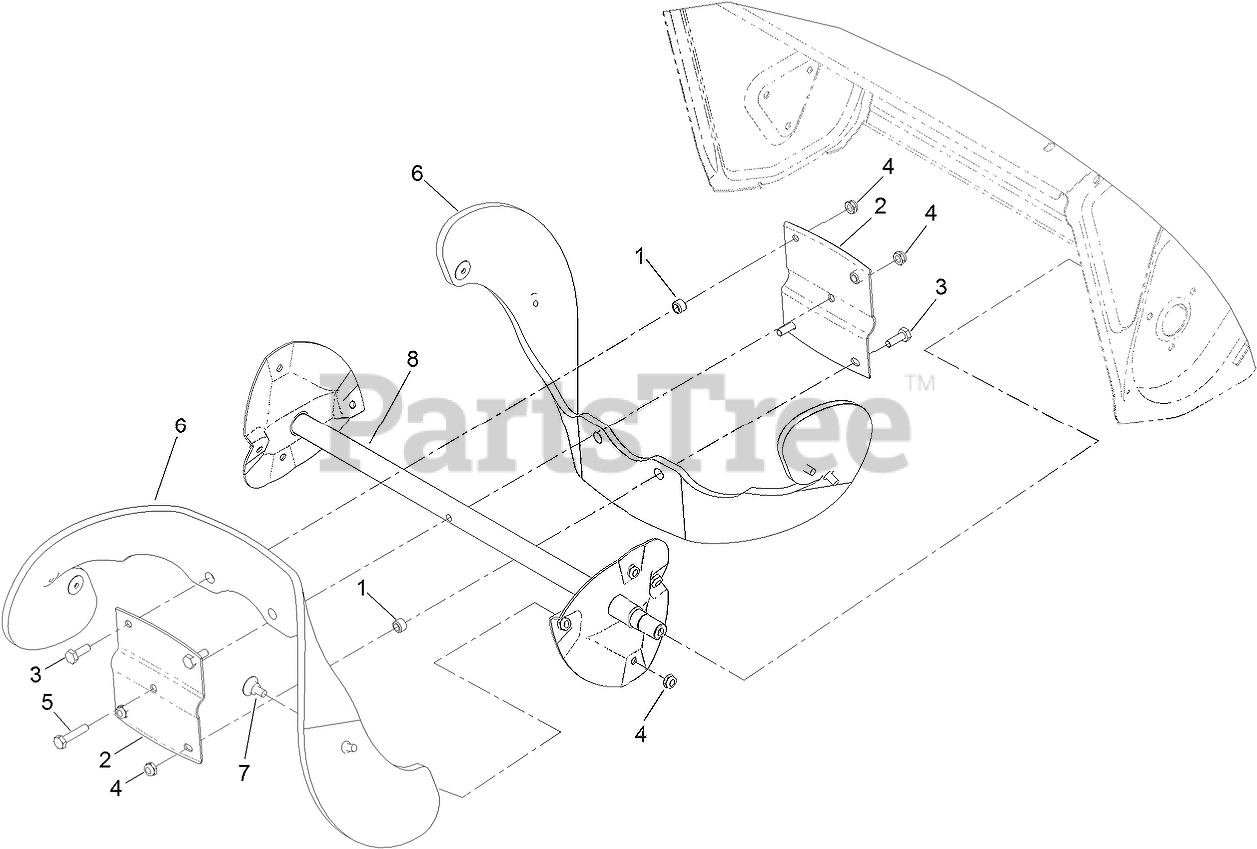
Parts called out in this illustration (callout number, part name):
1	SPACER-BLADE, ROTOR
2	HALF-ROTOR
3	SCREW-HH
4	NUT-LOCK, NI
5	SCREW-HH
6	BLADE-ROTOR
7	SCREW
